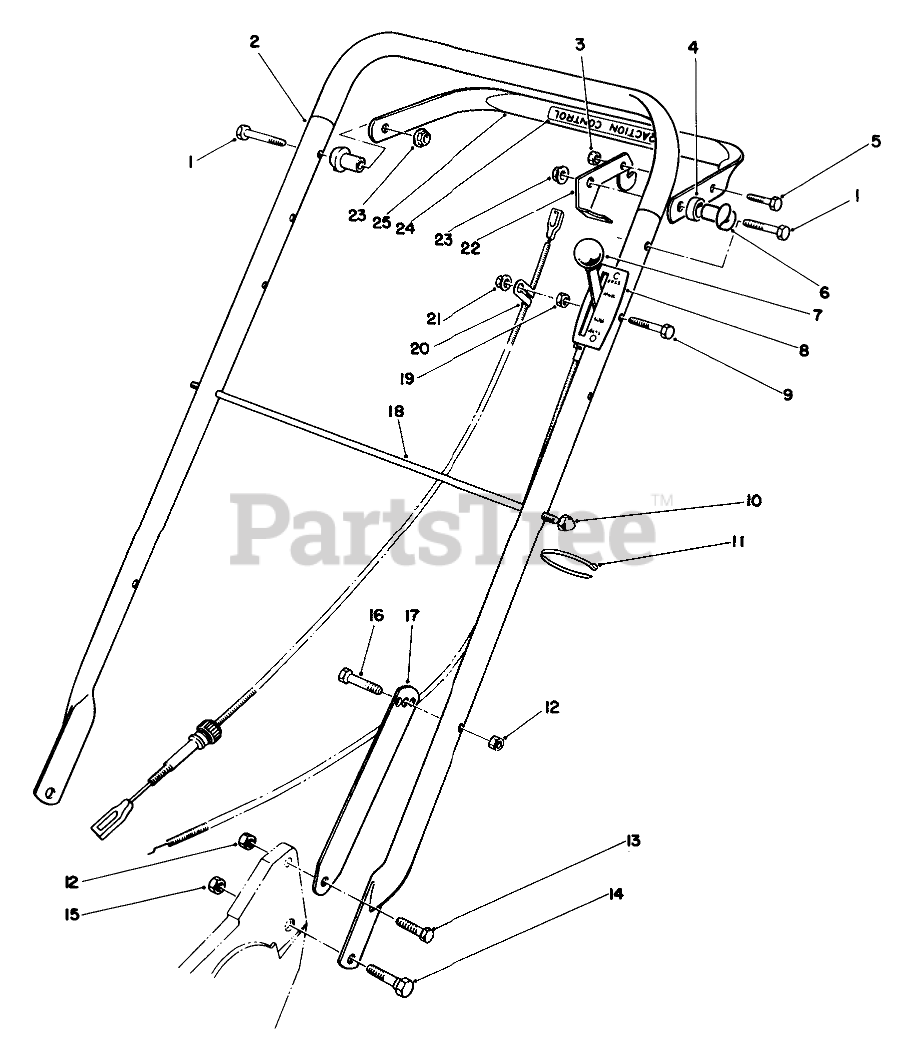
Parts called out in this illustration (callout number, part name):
1	SCREW-HH
2	HANDLE
3	NUT-LOCK, NI
4	SPACER-NYLON
5	SCREW-HH
6	SPACER-SUPPORT
7	KNOB-CONTROL
8	THROTTLE CONTROL
9	SCREW-HH
10	NUT-CAP
11	TIE-CABLE
12	NUT-LOCK, NI
13	SCREW-HH
14	SCREW-SHOULDER
15	NUT-LOCK, CONE
16	SCREW-HH
17	Latch-Handle
18	ROD-SUPPORT, BAG
19	NUT-JAM
20	TRACTION CABLE
21	NUT-LOCK, HHF
22	Lever-Control
23	NUT-HF
24	TRACTION DECAL
25	Bar-Control
